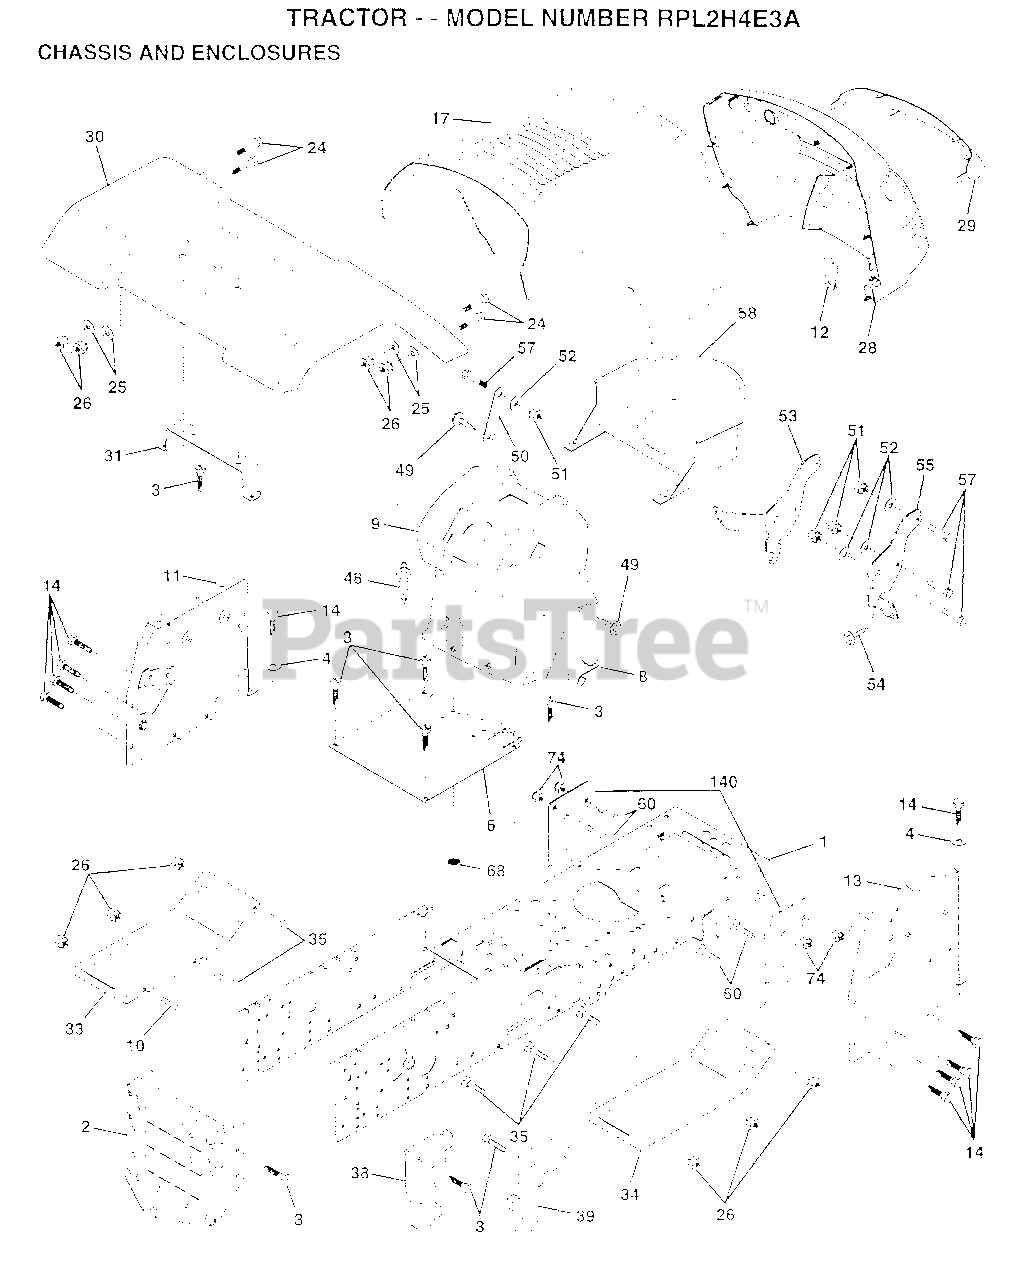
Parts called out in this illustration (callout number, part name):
1	CHASSIS WLDMT 11G
3	SCREW
4	WASHER
8	"CLIP,INSULATOR"
11	PANEL.DASH.LH.
12	CLIP.TINNERMAN
13	PANEL.DASH.RH
14	SCREW LT
24	BOLT
25	WASHER
26	NUT
29	LENS GRILLE
30	FENDER
31	BRKT FENDER
33	FOOTREST LH
34	FOOTREST RH
35	BOLT
38	BRACKET ASM LH
39	BRACKET ASM RH
48	RIVET.PUSH.PLATE
49	SCREW HEX CRT
50	BRACE SUPT DASH
51	NUT
52	WASHER
53	BRACKET.GRILLE.LH
55	BRACKET.GRILLE.RH
58	LENS.BAR.LR.NATURAL.LT.GRAY
60	BOLT
68	NUT
